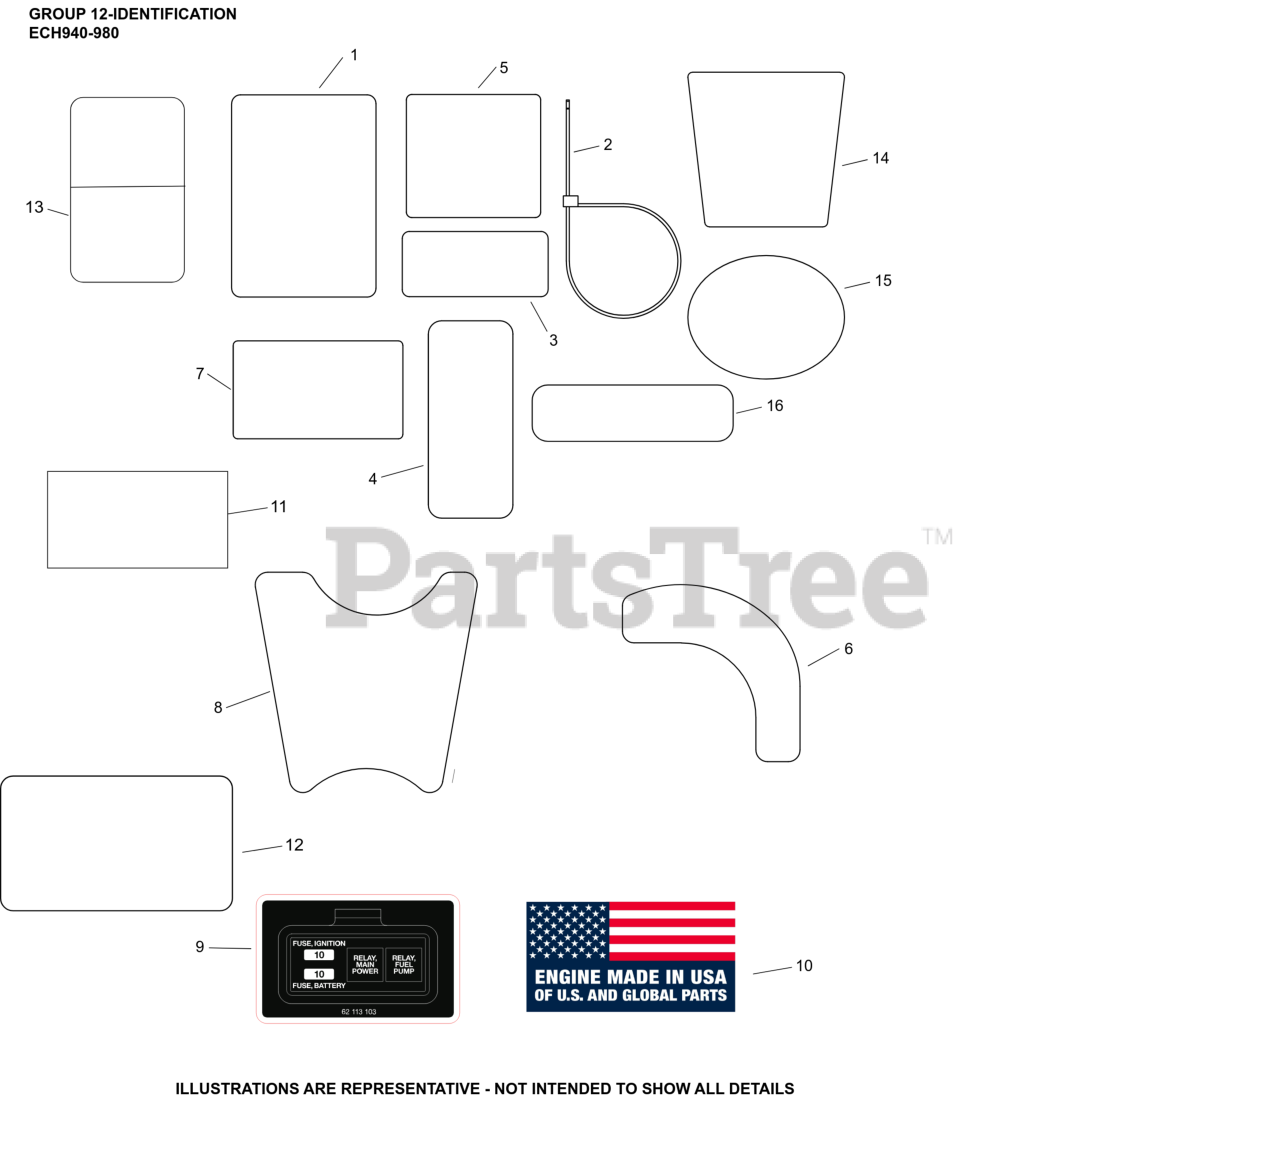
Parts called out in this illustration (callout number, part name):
1	LABEL, CLEAR LAMINATION
3	LABEL, EFI FUEL FILTER
5	DECAL, HORSEPOWER & DISPLACEMENT
10	DECAL, USA
13	HOT SURFACE DECAL
